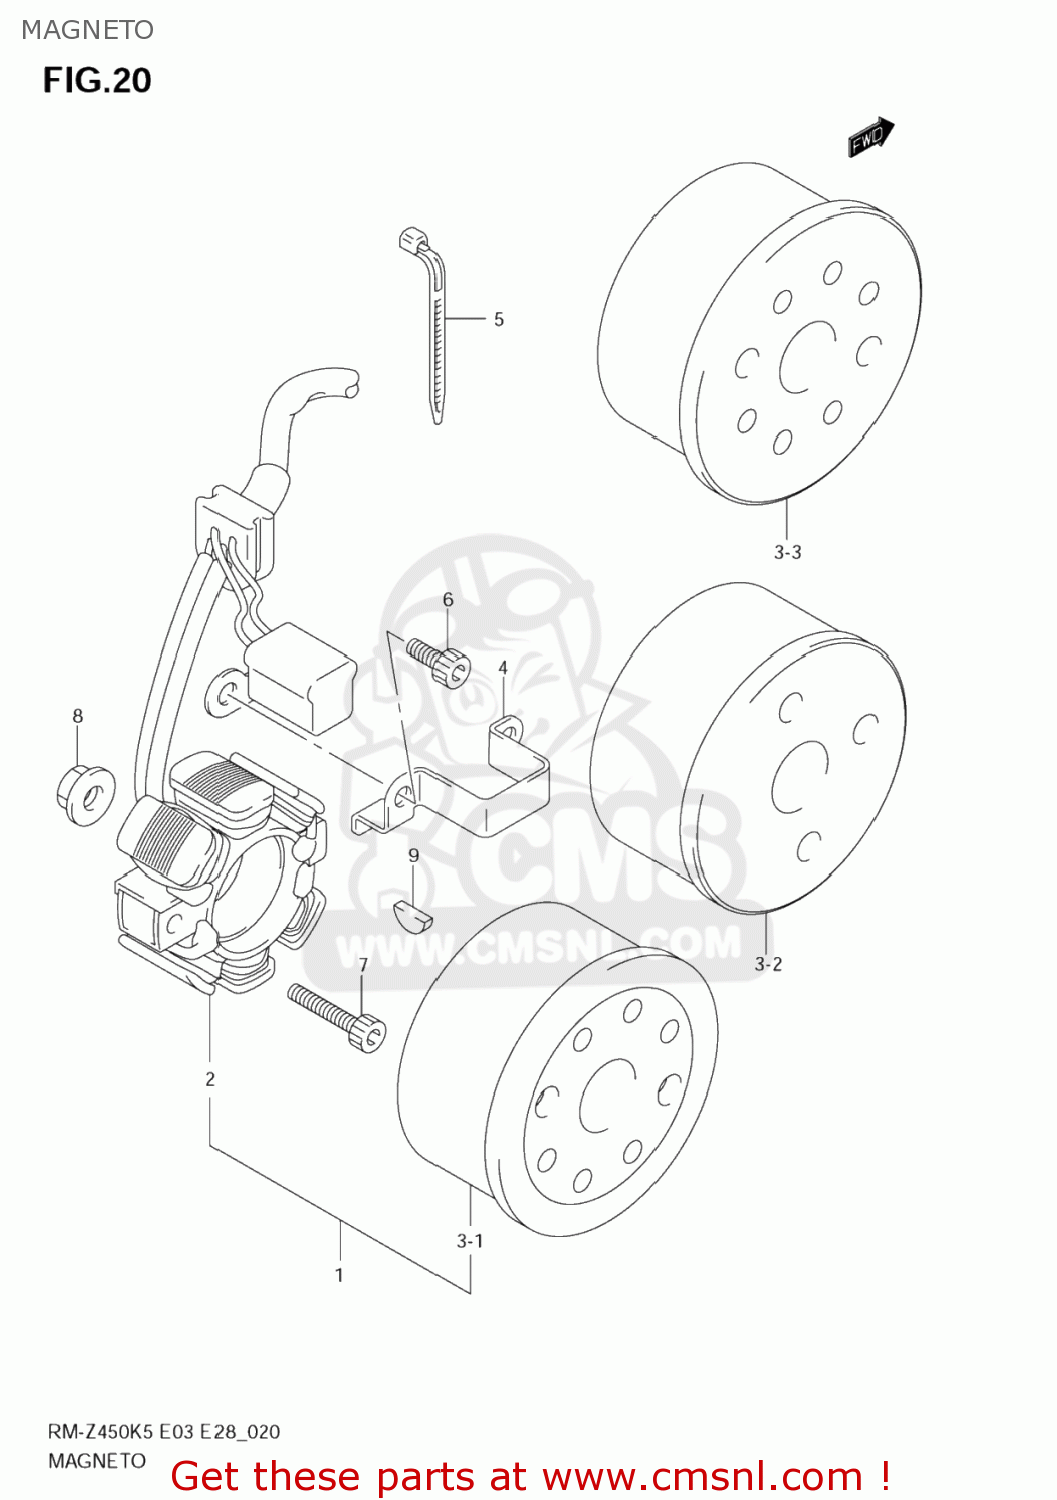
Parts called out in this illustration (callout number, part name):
1	MAGNETO ASSY
2	STARTER ASSY
3	ROTOR ASSY
4	CLAMP,MAGNETO LEAD
5	CLAMP(L:125)
6	BOLT
7	BOLT(5X25)
8	NUT
9	KEY
